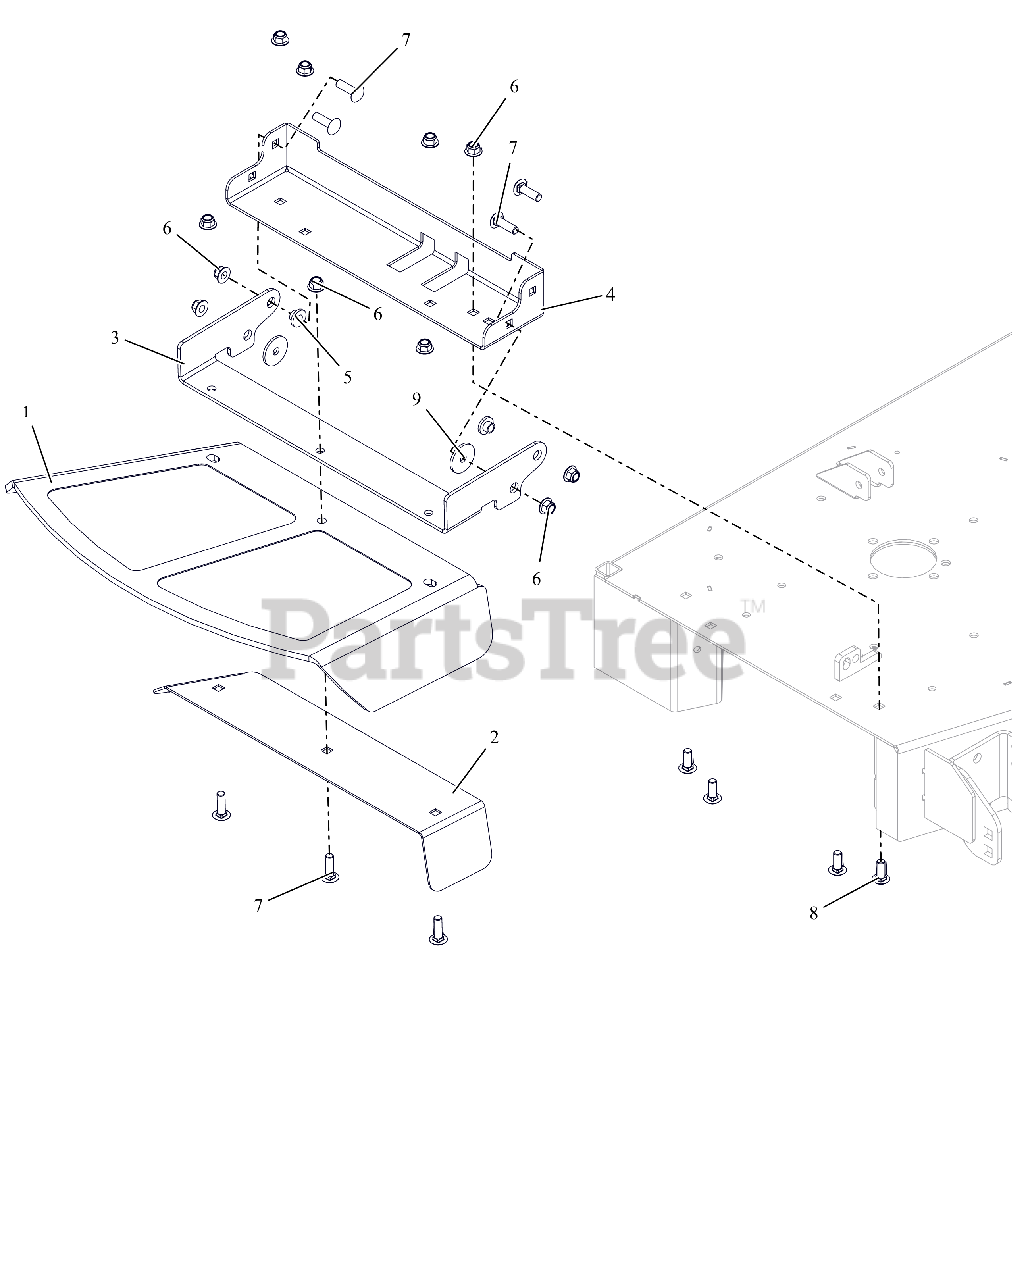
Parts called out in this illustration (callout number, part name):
1	CHUTE,48-60" FRMD RUBBER DISCH
2	PLT, DISCH. CHUTE CLMP-CE
3	BRKT, CE CHUTE MTG
4	WMT, DISCH. CHUTE-CE-W/SAFETY
5	BSHG-FLG .385X.500X.875X.406
6	NUT,NYL-FLG .38-16 GF ZCC
7	BLT,RHSSN .38-16X1.25 G5 ZCC
8	BLT,RHSSN .38-16X1.00 G5 ZCC
9	WSHR, FLT .380X1.50X.125 ZCC
